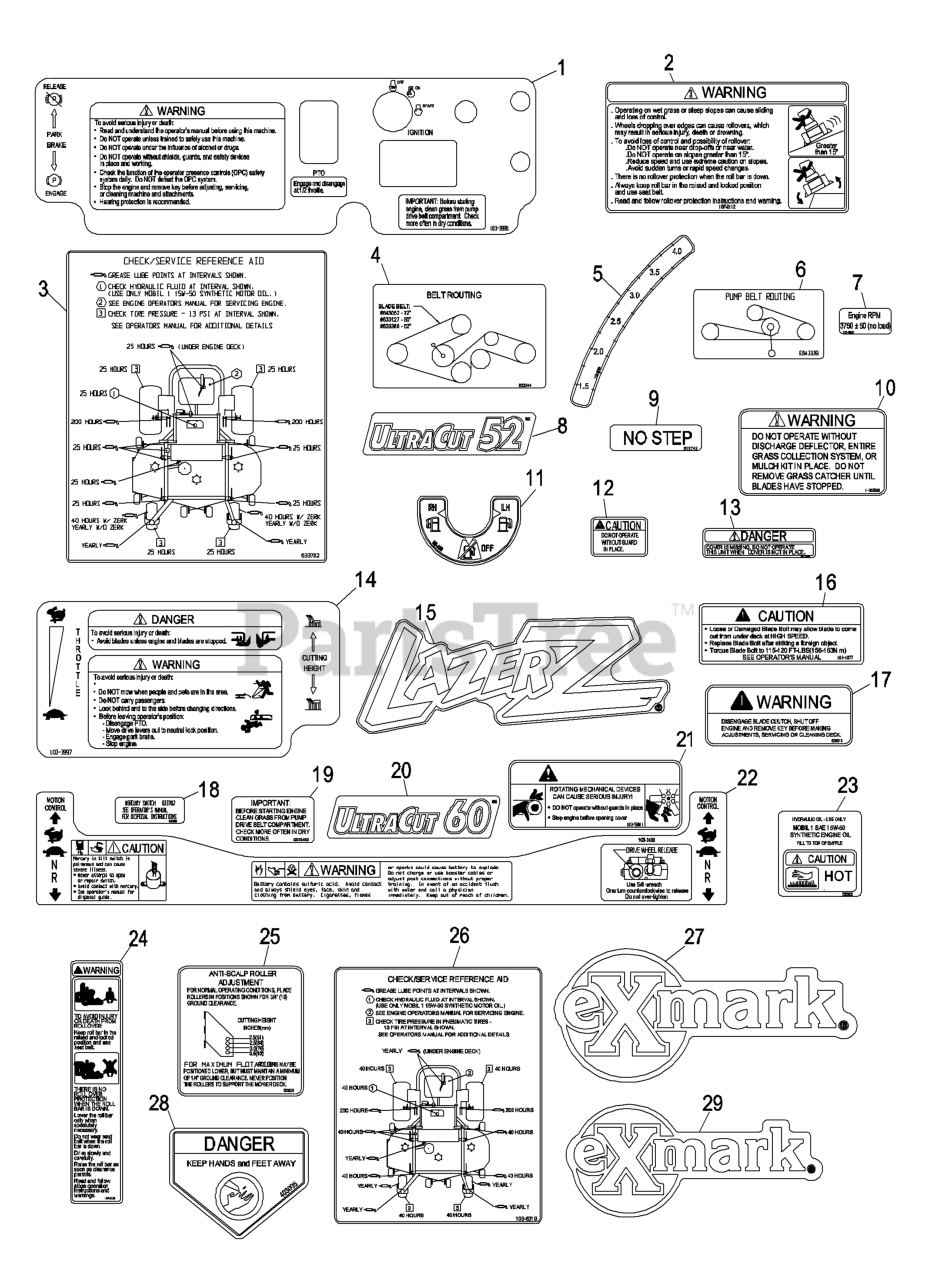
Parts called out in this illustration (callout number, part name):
1	DECAL,CONSOLE
2	DECAL-WARNING
3	DECAL,CHECK/SERVICE
4	DECAL,BELT ROUTING
6	DECAL-ROUTING, BELT
8	DECAL,ULTRACUT 52
9	DECAL,NO STEP
10	DECAL-WARNING, DISCHARGE
11	DECAL-VALVE, FUEL
12	DECAL-GUARD
13	DECAL-COVER, MISSING
15	DECAL,LAZER MODEL
16	DECAL,BOLT TORQUE
17	DECAL,WARNING
18	DECAL-SWITCH, MERCURY
19	DECAL-IMPORTANT
20	DECAL,ULTRACUT 60
21	DECAL-DEVICES, ROTATING
24	DECAL-WARNING, FOLDING RO
25	DECAL,ANTISCALP
26	DECAL,CHECK SERVICE LZ
27	DECAL,EXMARK LOGO
28	DECAL-DANGER
29	DECAL,EXMARK LOGO
